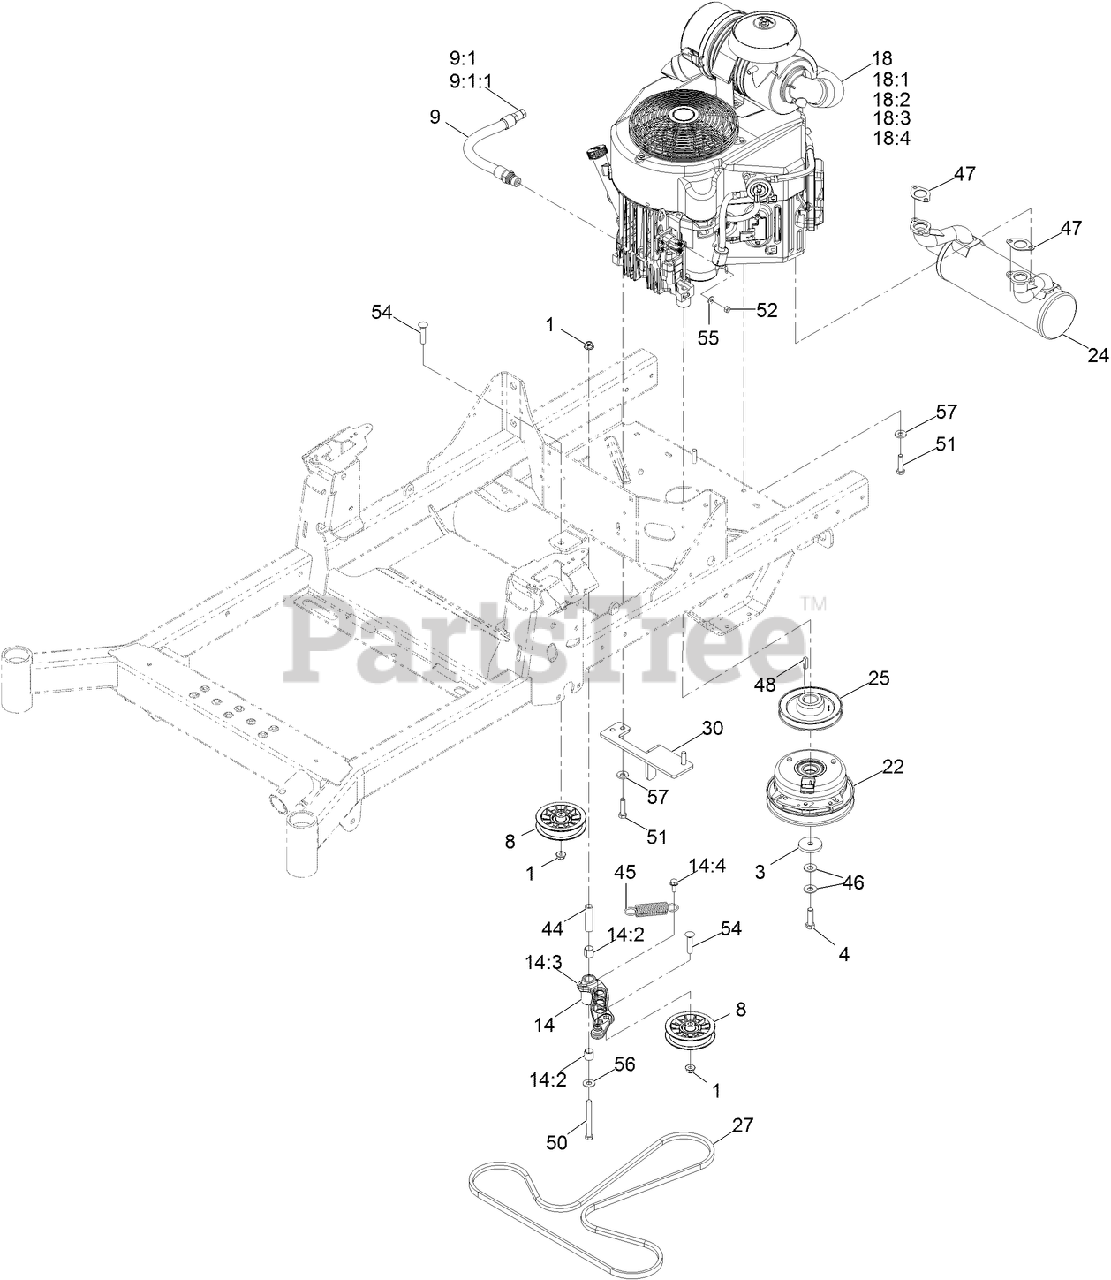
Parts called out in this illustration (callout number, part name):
1	NUT-HF, NI
3	WASHER-CLUTCH
4	SCREW-HH, W/LOCTITE
8	PULLEY-FLAT IDLER
9	ENGINE OIL DRAIN HOSE ASM
9:1	PLUG-HH
9:1:1	O-RING
14	IDLER ARM ASM
14:2	SLEEVE-BEARING
14:3	FITTING-GREASE, 90 DEG
14:4	SCREW-THD ROLL, HWH
18:1	KAWASAKI 49065-7007 ENGINE OIL FILTER
18:2	KAWASAKI 49019-7005 FUEL FILTER
18:3	KAWASAKI 11013-7045 SAFETY FILTER
18:4	KAWASAKI 11013-7044 ENGINE AIR FILTER
22	CLUTCH
24	MUFFLER
25	SHEAVE (W/HUB)
27	BELT-V
30	ANCHOR-CLUTCH
44	BUSHING-PIVOT, IDLER
45	SPRING-EXTENSION
46	WASHER-SPRING
47	GASKET-EXHAUST
50	SCREW-HH
51	SCREW-HH
52	NUT-HEX
54	SCREW-CARR
55	WASHER-FLAT
56	WASHER-FLAT
57	WASHER-BELLEVILLE
